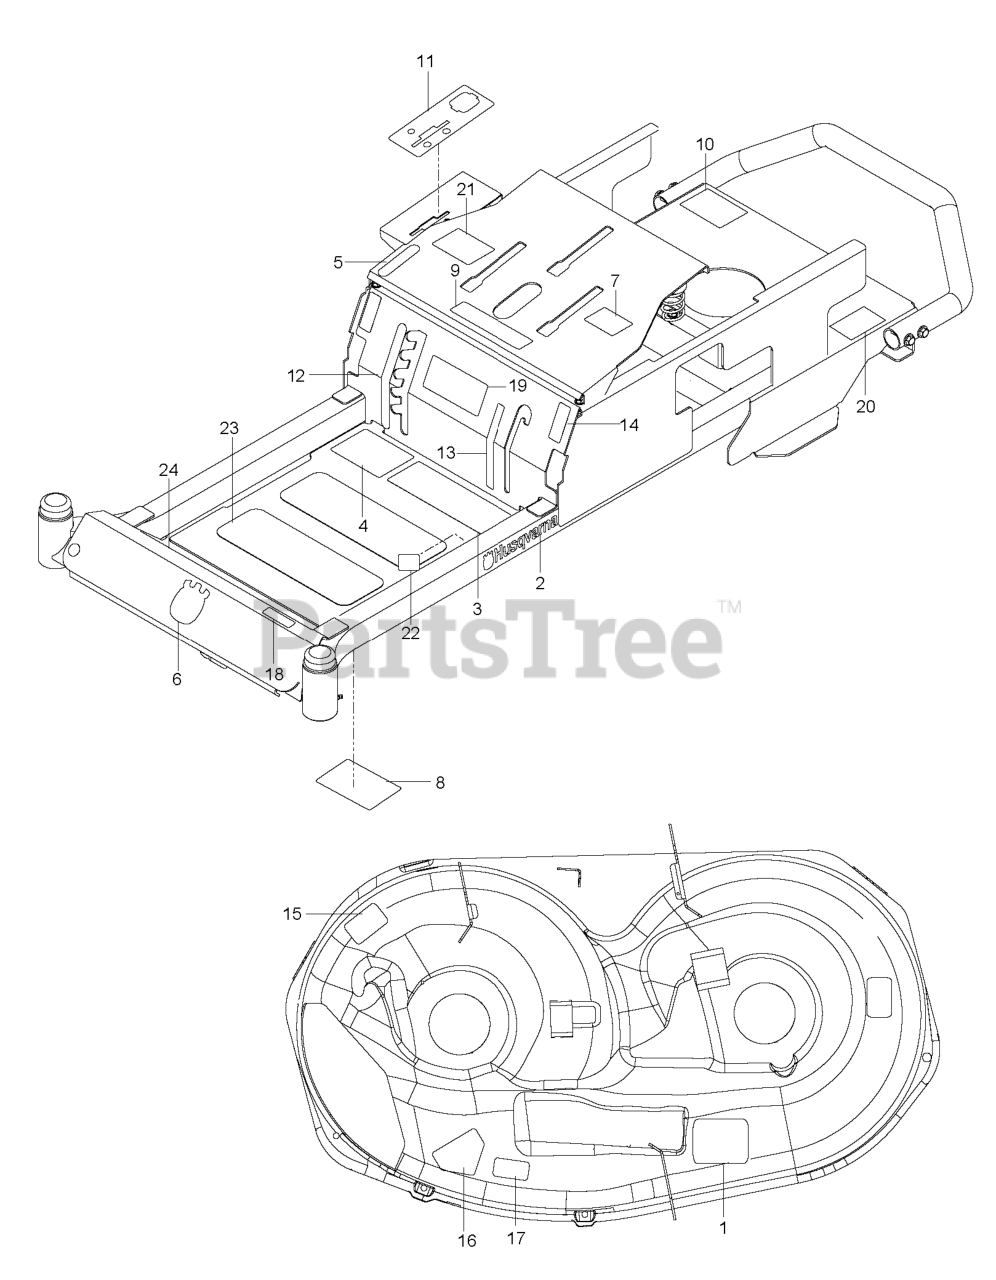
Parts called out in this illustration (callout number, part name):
1	DECAL, BELT ROUTING
2	RP.DECAL.BADGE.170MM.TEXTLOGO
3	DECAL, SAFETY WARNING
4	DECAL, WARNING
5	DECAL, PARK BRAKE
6	DECAL.AUGER.HUSQ.CROWN.SNOW
7	DECAL, EXITING MOWER
8	DECAL, SERVICE
9	EURO DECAL-BATTERY WARNIN6
10	DECAL, DO NOT TOW
11	DECAL, CONTROL PANEL HUS
12	DECAL, DECK HEIGHT
13	DECAL, BLADE ENGAGEMENT
14	DECAL, MOTION CONTROL
15	DECAL, CAUTION
16	DECAL, CPSC
17	DECAL, EURO SEVERING
18	DECAL RZ4221
19	DECAL, START
20	DECAL, ECM, AUSTRALIA
21	DECAL, CUSTOMER RESPNSIBILITY
22	DECAL 80 DBA
23	ANTI-SKID PAD
